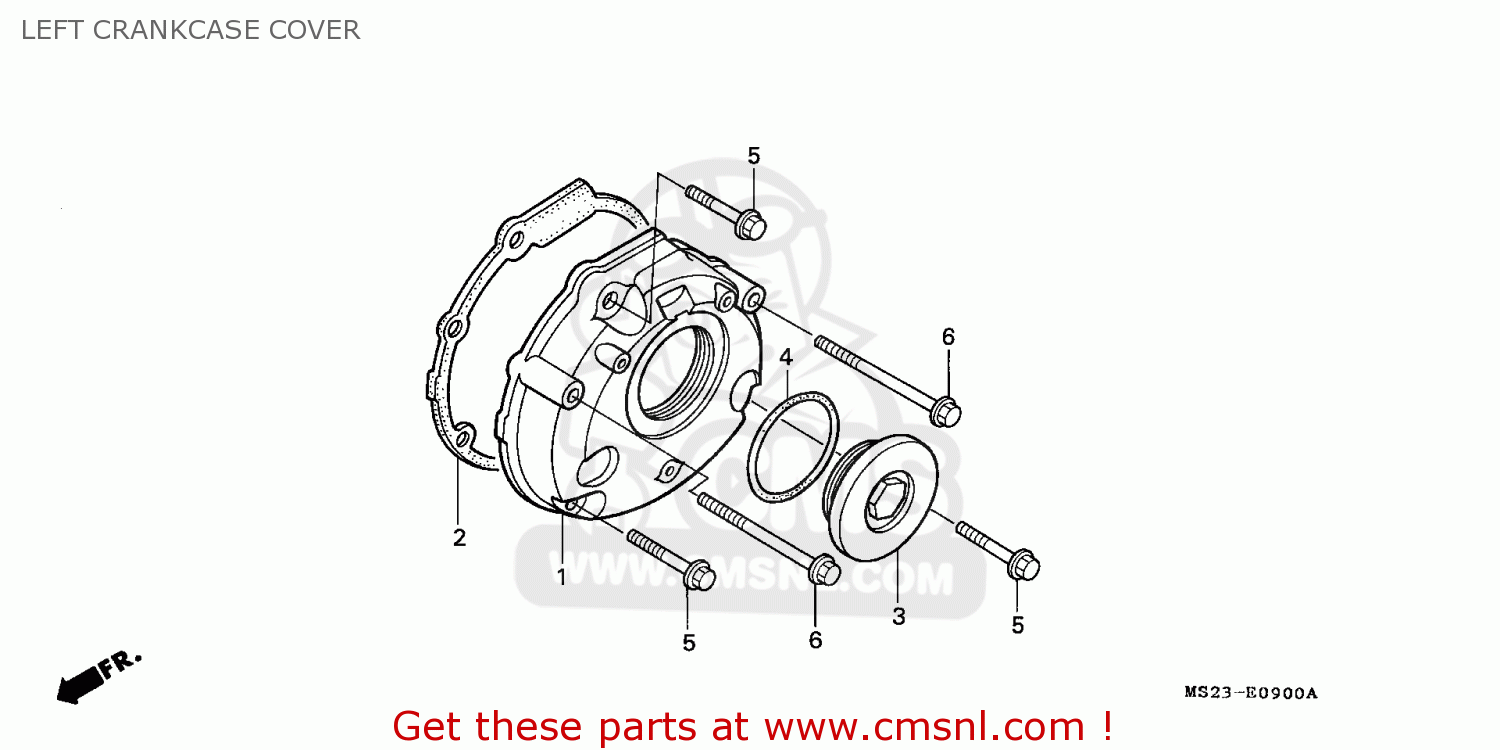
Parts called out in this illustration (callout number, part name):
1	COVER,L.CRANKCASE
2	GASKET,L CRANKCAS (MCA)
3	CAP,45MM
4	O RING,48.1X3.6
5	BOLT,FLANGE,SH,6X25
6	BOLT,FLANGE,SH,6X40
